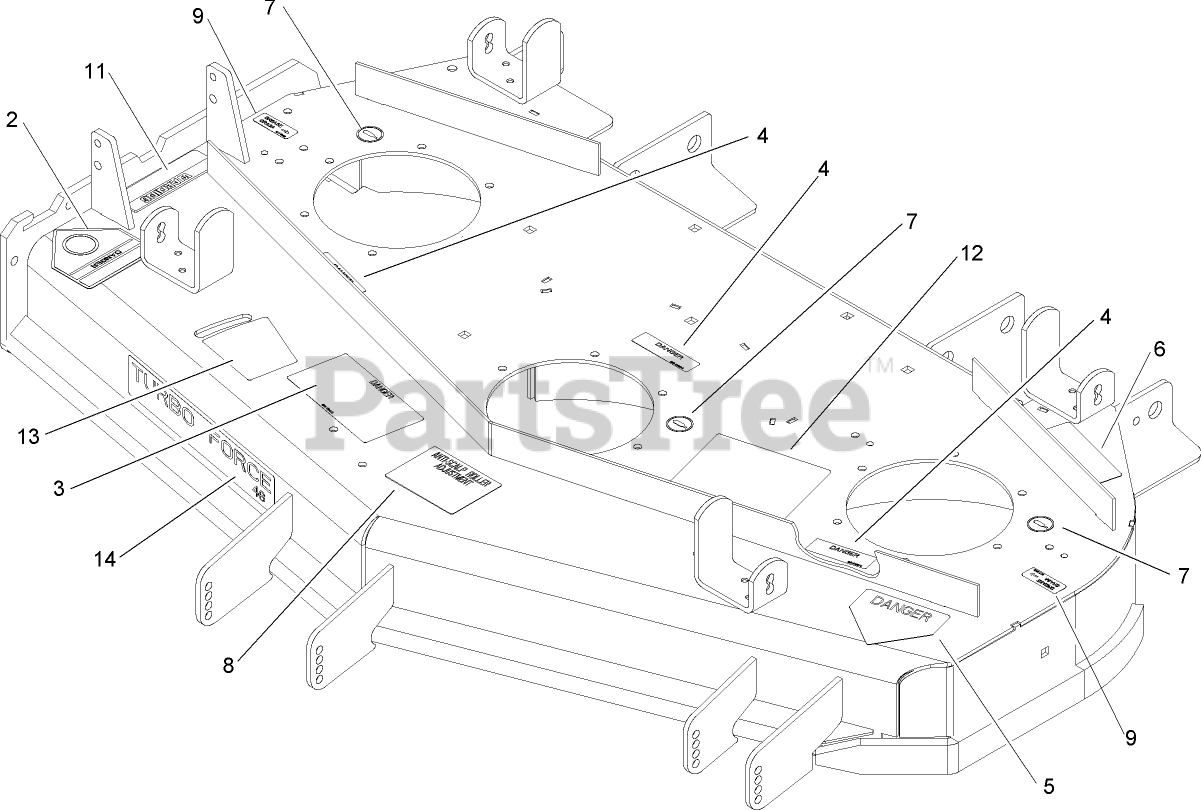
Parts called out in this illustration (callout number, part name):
2	DECAL-DANGER
3	DECAL-DANGER, THROWN OBJECT
4	DECAL-COVER, MISSING
5	DECAL-DANGER
6	DECAL-TORQUE
7	DECAL-GREASE
8	DECAL-SCALP, ANTI
9	Decal-Grease
11	DECAL-WARNING
12	DECAL-AID, SERVICE
13	DECAL-ADJUSTMENT, BAFFLE
